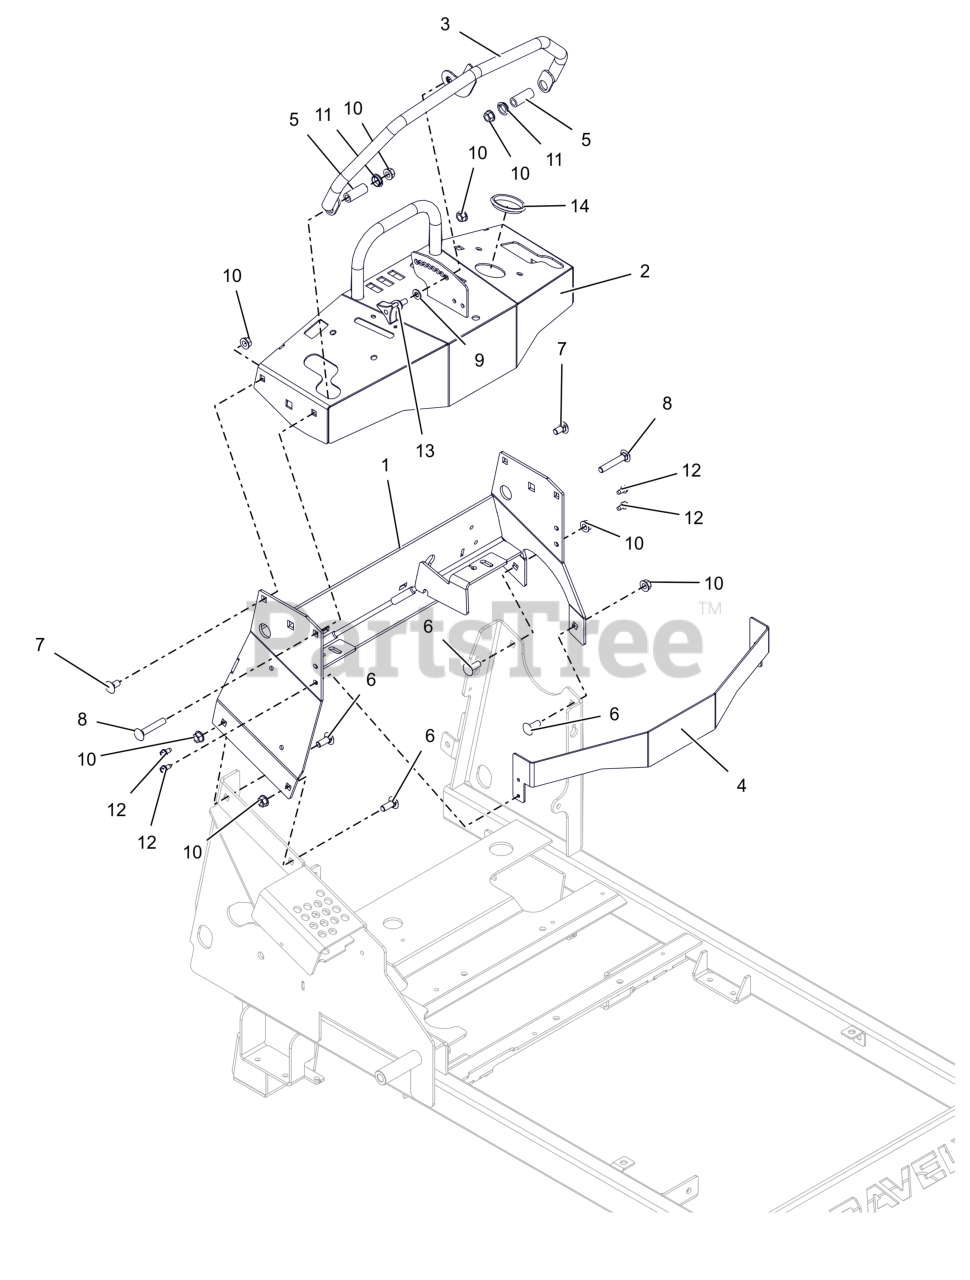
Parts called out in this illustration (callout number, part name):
1	KIT,PROSTANCE TOWER WITH DECAL
2	WLDMT, DASH (RED)
3	WLDMT, CRUISE BAR
4	PLATE, DASH - ACCENT (BLACK)
5	SPACER, .375 X .625 X 1.54
6	BLT,RHSSN .38-16X1.00 G5 ZCC
7	BLT, RHSN .38-16X.750 G5 ZCC
8	BLT,RHSN .38-16X2.25 G5 ZCC
9	WSHR,FLT .344X.688X.065 ZCC
10	NUT-LK-CTR-FLG .375-16 GF ZCC
11	BUSHING, POLYLINER-.63 SNAPIN
12	SCR-TAP .25-20X.50 HWH ZCC
13	KNOB,WING STUD 5/16-18 X .75
14	GROMMET, RUBBER 1.89 ID
